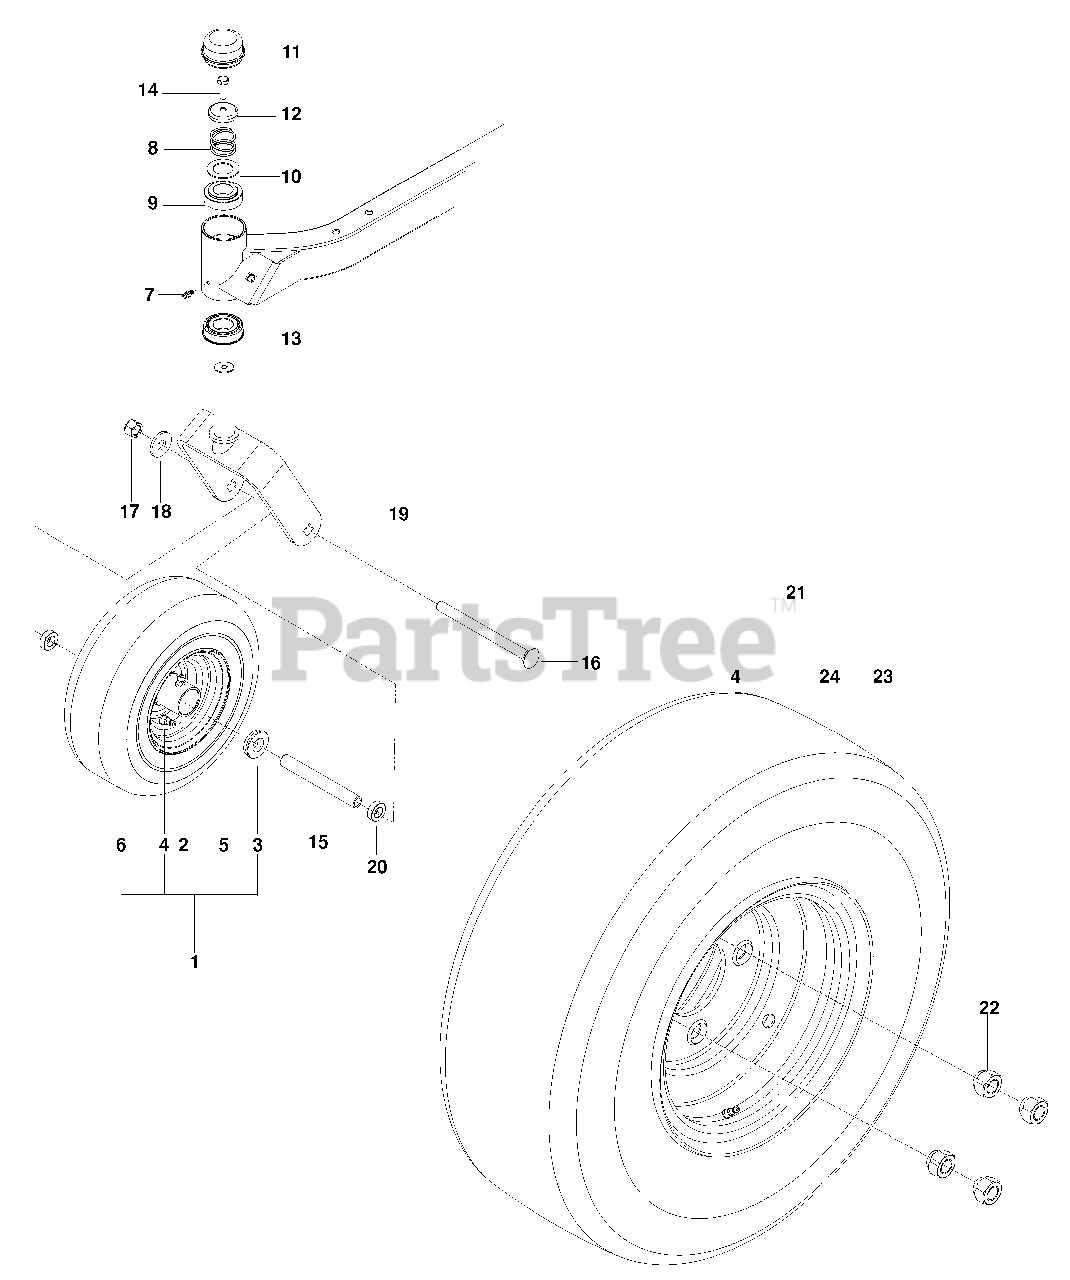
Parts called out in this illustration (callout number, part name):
1	CASTER TIRE ASSY
2	ZERK
3	BEARING, FLANGED
6	TIRE
7	ZERK
8	SPRING, CASTER
9	BUSHING, CASTER
11	CAP, GREASE
12	PLUG, CASTER
13	BEARING, FLANGED
14	HHB 5/16-18 x 1 NYLOC
16	RHSNB 1/2-13 x 6 1/2
17	NUT 1/2 HEX NYLOC
18	WASHER 1/2 FLAT
19	YOKE, CASTER
20	SPACER 5/16
21	WHEEL ASSY REAR
22	NUT 1/2 LUG
23	TIRE 4 PLY 18 x 7.5 x 8
